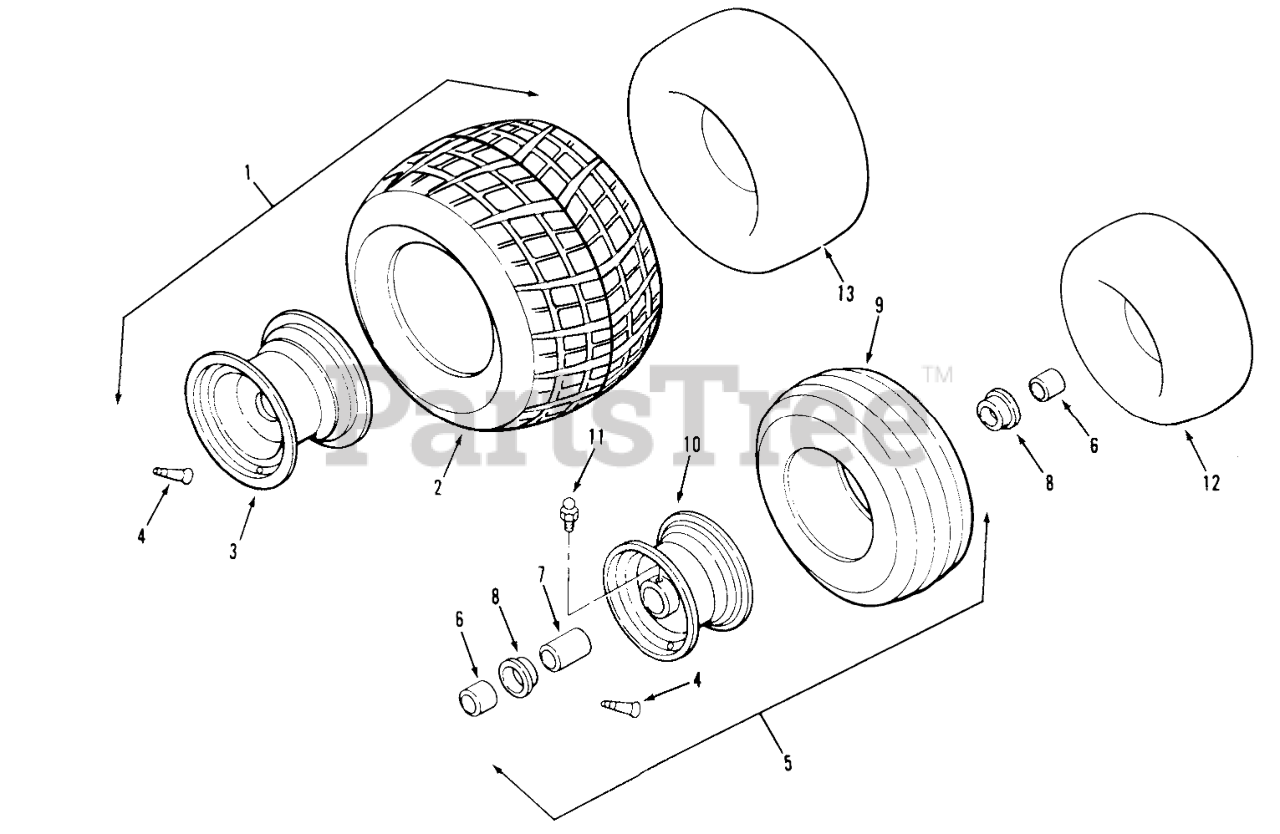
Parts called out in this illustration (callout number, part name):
2	TIRE 22 X 11.00-8
3	Wheel-Rear, Silver
4	VALVE
6	SPACER
7	SPACER FRT WHEEL INN
8	BEARING BALL
9	TIRE-FRT 13X5.00-6
10	WHEEL FT SLUV 10239K
11	Zerk
12	INNER TUBE
13	Tube-Rear
